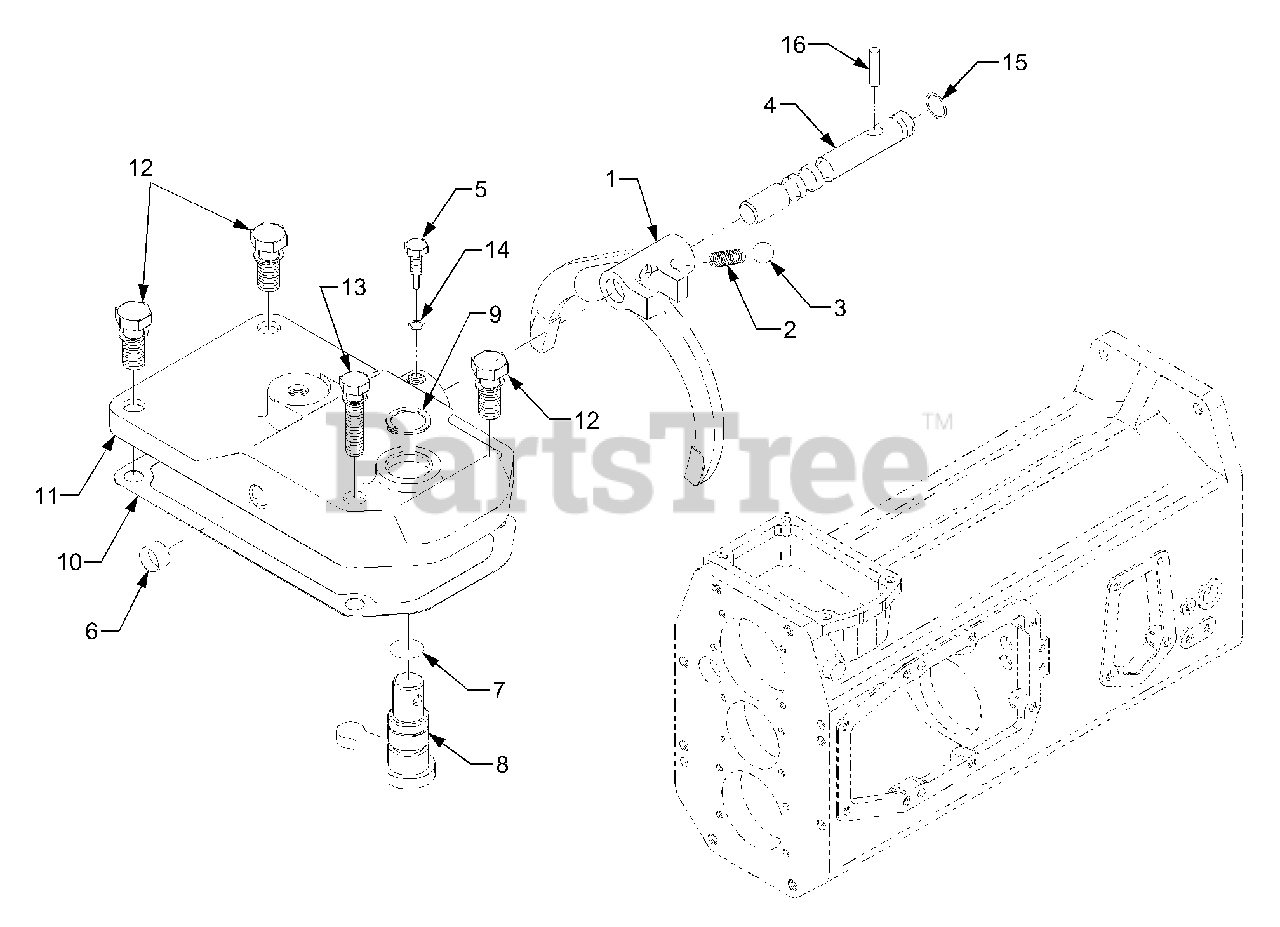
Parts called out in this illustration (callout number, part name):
1	Fork, Shift (Shuttle)
4	Rod, Fork (Shuttle)
8	Arm, Shift (Shuttle)
11	Cover, Shift (Shuttle)
16	Pin, Straight
